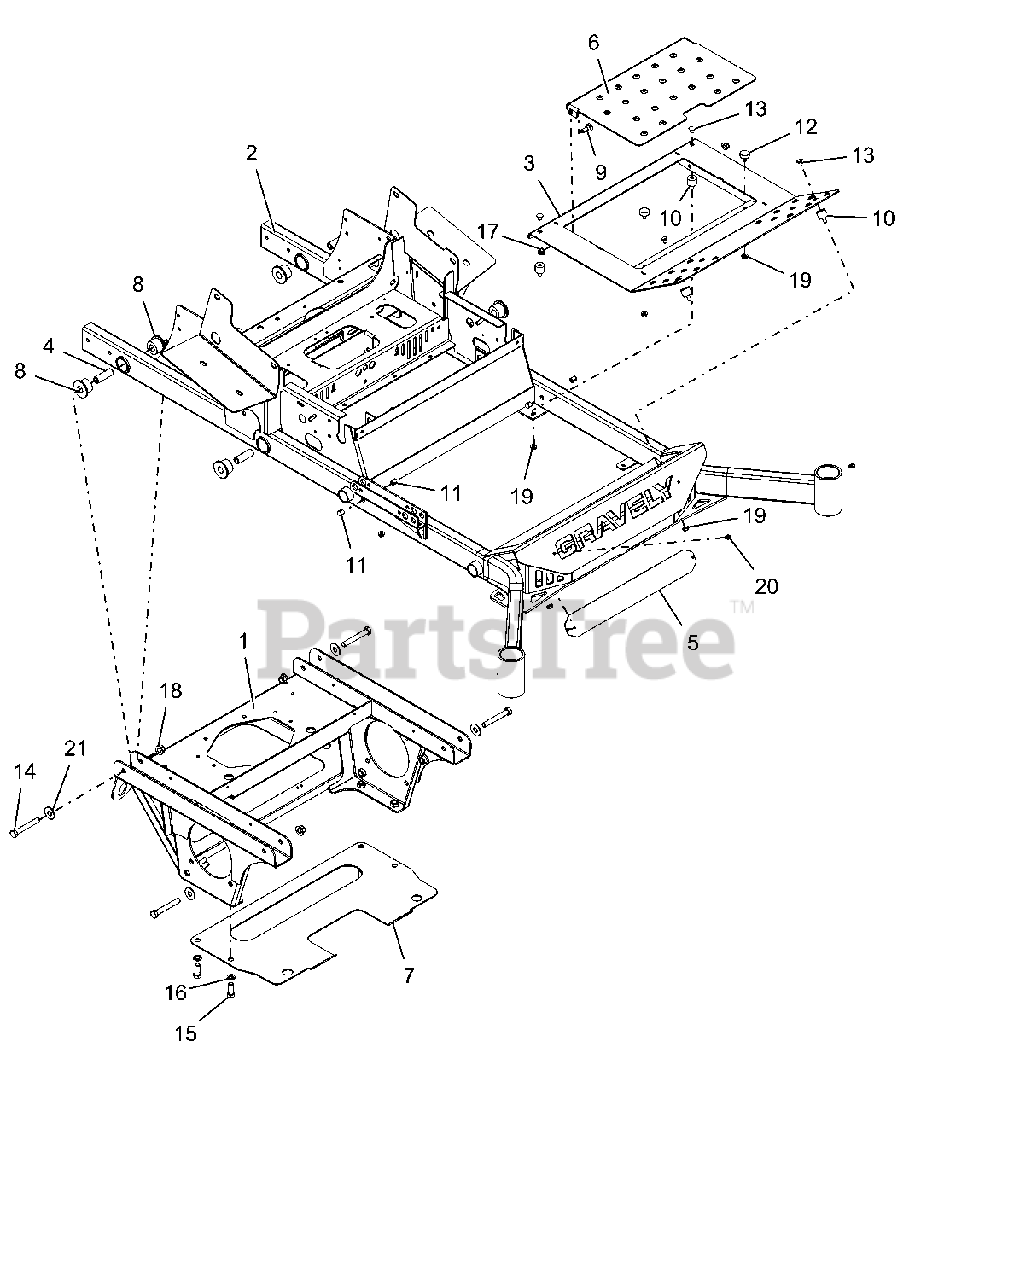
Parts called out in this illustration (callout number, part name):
1	PT200/400 AXLE/ENG FRM WMT-RED
2	72" PT200/400 FRAME W/DECALS
3	FOOTPLATE WLDMT W/SAFETY DECAL
4	BSHG-SLV .50X.75X2.23
5	BUMPER LOGO BACKING PLATE -BLK
6	INSPECTION PANEL W/SAFTY DECAL
7	PLATE-TRANSMISSION SKID
8	BSHG-FLG .75X1.51X1.13X2.0 URE
9	BLT,SHLDR EP .38-16X.30 HEX YZ
10	BUMPER,STUD MNTD W/FEMALE INSR
11	PLUG, HOLE .50
12	BUMPER, RUBBER
13	BLT-RDHDSQNK .31-18X.50 G5YZ
14	BLT-HEX .50-13X3.50 GR5 YWZC
15	BLT-HEX .50-13X1.25 GR5 YWZC
16	WSHR-LK .50X.125 REG YWZC
17	NUT-LK-NYL-FLG .38-16 YWZC
18	NUT-LK-NYL-FLG .50-13 YWZC
19	NUT-SPNLK-FLG .312-18 YWZC
20	SCR-TAP .25-20X.50 HWH TR YWZ
21	WSHR-FL-STL.563X1.38X.109YWZC
